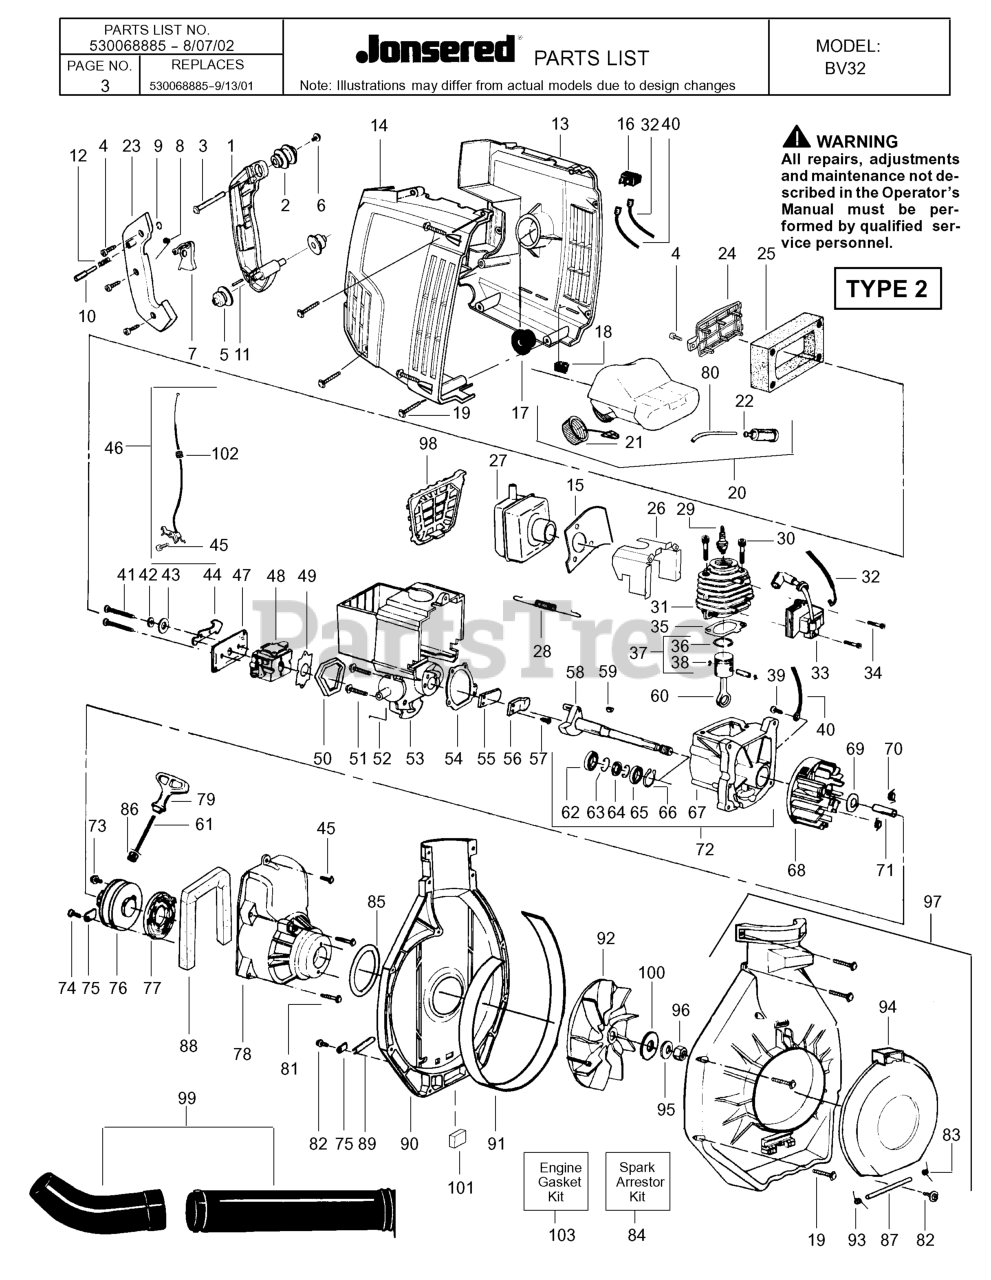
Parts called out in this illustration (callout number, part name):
1	HANDLE KIT
3	SPACER-ISOLATOR
4	SCREW-10-14X5/8 PHIL.FI
5	ISOLATOR-HANDLE (REAR)
6	SCREW-10-24 X 3/8
8	SPRING-LEVER RETURN
9	C CLIP-THROTTLE LOCK
10	BUTTON-THROTTLE LOCK
11	HANDLE PIN
12	SPRING-THROTTLE
15	HEAT SHIELD/AIR DAM
17	ISOLATOR-ENGINE MOUNT
18	ISOLATOR-TANK
20	ASSY-FUEL TANK W/RETAIN
21	CAP ASSY W/ RETAINER
22	FUEL PICK-UP ASSY
23	ASSY-COVER & THROTTLE LOCK
25	AIR FILTER
26	AIR BAFFLE
28	SPRING-MUFFLER
30	SCREW 1/4-20 X 7/8
31	CYLINDER
32	WIRE-LEAD (SWITCH)
33	IGNITION MODULE.
34	SCREW
35	GASKET-CYL W/ADHESIVE
36	RING-PISTON (HOOKED)
37	KIT-PISTON (32CC)
38	WRIST PIN RET.
39	SCREW(10-24 X 7/16 HEX
40	WIRE-GROUND (SWITCH)
43	CHOKE SPACER
44	SHUTTER-CHOKE
45	SCREW 8-16 X 9/16 (PLAS
46	THROTTLE CABLE
47	PLATE-AIR FILTER MTG
48	CARB ASS'Y WT-141A
49	GASKET-CARB
50	SEAL-FOAM/REED BLOCK
51	SCREW 1/4-20 X 7/8 (TAP
52	WIRE-GROUND/STATIC
53	REED BLOCK/HEAT SHIELD
54	GASKET-REED BLOCK/C'CAS
55	VALVE-REED
56	REED STOP
58	ASSY-CRANKSHAFT
59	KEY-FLYWHEEL
60	ASS'Y-CONNECTING ROD
62	BEARING-R8 (INNER)
63	RING-RETAINING
64	SEAL-CRANKSHAFT
65	BEARING-R8 (OUTER)
66	RING-RETAINING (SHAFT)
67	ASSY-CRANKCASE
69	WASHER
70	SPRING STR DOG
71	SPACER-FLYWHEEL
72	ASSY-C'CASE & C'SHAFT
74	SCREW-10-16 X 1/2 HI-LO
77	STARTER SPRING
78	FAN HOUSING KIT
79	HANDLE-STARTER
81	SCREW-10-24X1-3/8-TAPTI
82	SCREW-10-16X1/2 HI-LO(S
83	SPRING-TORSION (LEFT)
84	SPARK ARRESTOR KIT
85	O-RING SEAL
86	EYELET-FLANGE
87	PIN-PIVOT
89	TUBE-ROPE RETAINER
90	HSG-BLOWER (UPPER) (BL)
91	BAND-BLOWER HSG
92	ASSY-IMPELLER
93	SPRING-TORSION (RIGHT)
95	WASHER CONICAL
97	BLOWER HOUSING ASSY - BLACK
98	MUFFLER GUARD
99	TUBE & NOZZLE ASS'Y
100	WASHER-IMPELLAR
102	GROMMET-CARB. BOX
103	KIT-GASKET
530047885	DECAL LOWER HOUSING
